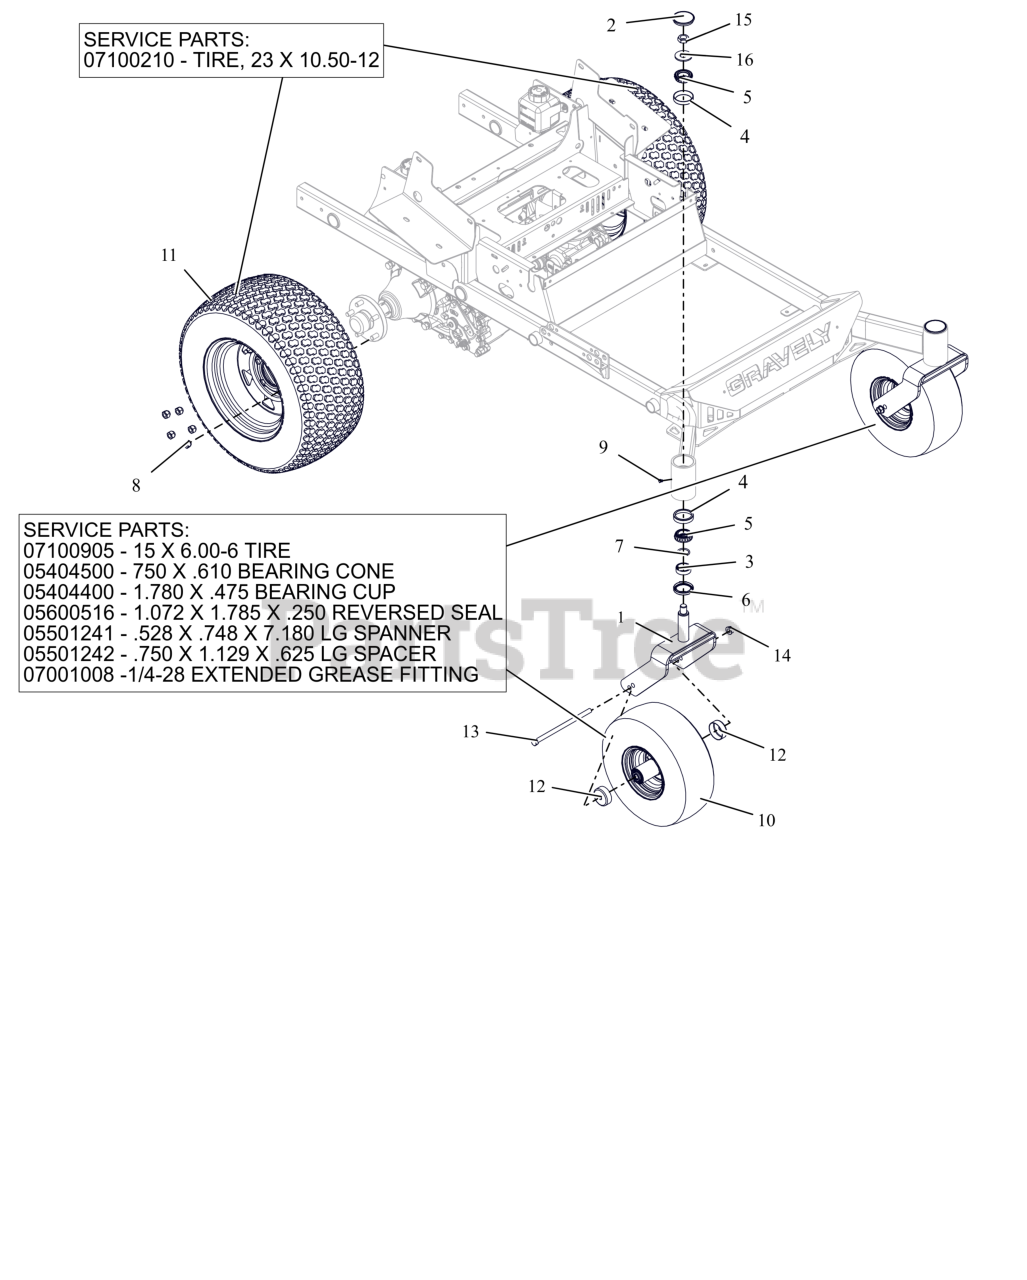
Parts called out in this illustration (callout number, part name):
1	CASTER FORK WMT - RED
2	CAP, DUST
3	SPCR, FRONT CASTER FORK
4	BRG-CUP 2.328X.465
5	BRG-CONE 1.25X.66
6	SEAL, OIL 1.75 X 2.332 X .312
8	NUT, WHEEL .50-20 ZCC
9	FTG, .25-28 FLUSH MNT GREASE
10	ASM, WHL/TIRE 15X6.00-6 SMOOTH
10	TIRE, 15X6-6 SMOOTH
10	BRG-CONE .750X.61
10	BRG-CUP 1.781X.475
10	SEAL,1.072X1.785X.250 REVERSED
10	SPANNER, .528X.748X7.18 LG
10	SPACER, .750X1.129X.625 LG
10	GREASE FITTING 1/4-28 EXTENDED
11	ASM, WHL/TIRE 23X10.50-12 K500
11	TIRE, 23X10.00-12
12	SHIELD, WHEEL BEARING
13	BLT, HEX .50-13X9.00 G5 ZCC
14	NUT-LK-TOP-FLG .500-13 GF ZCC
15	NUT, JAM-TOPLOCK .750-16 ZCC
16	WSHR-FL-STL 0.812X2X0.148 ZCC
